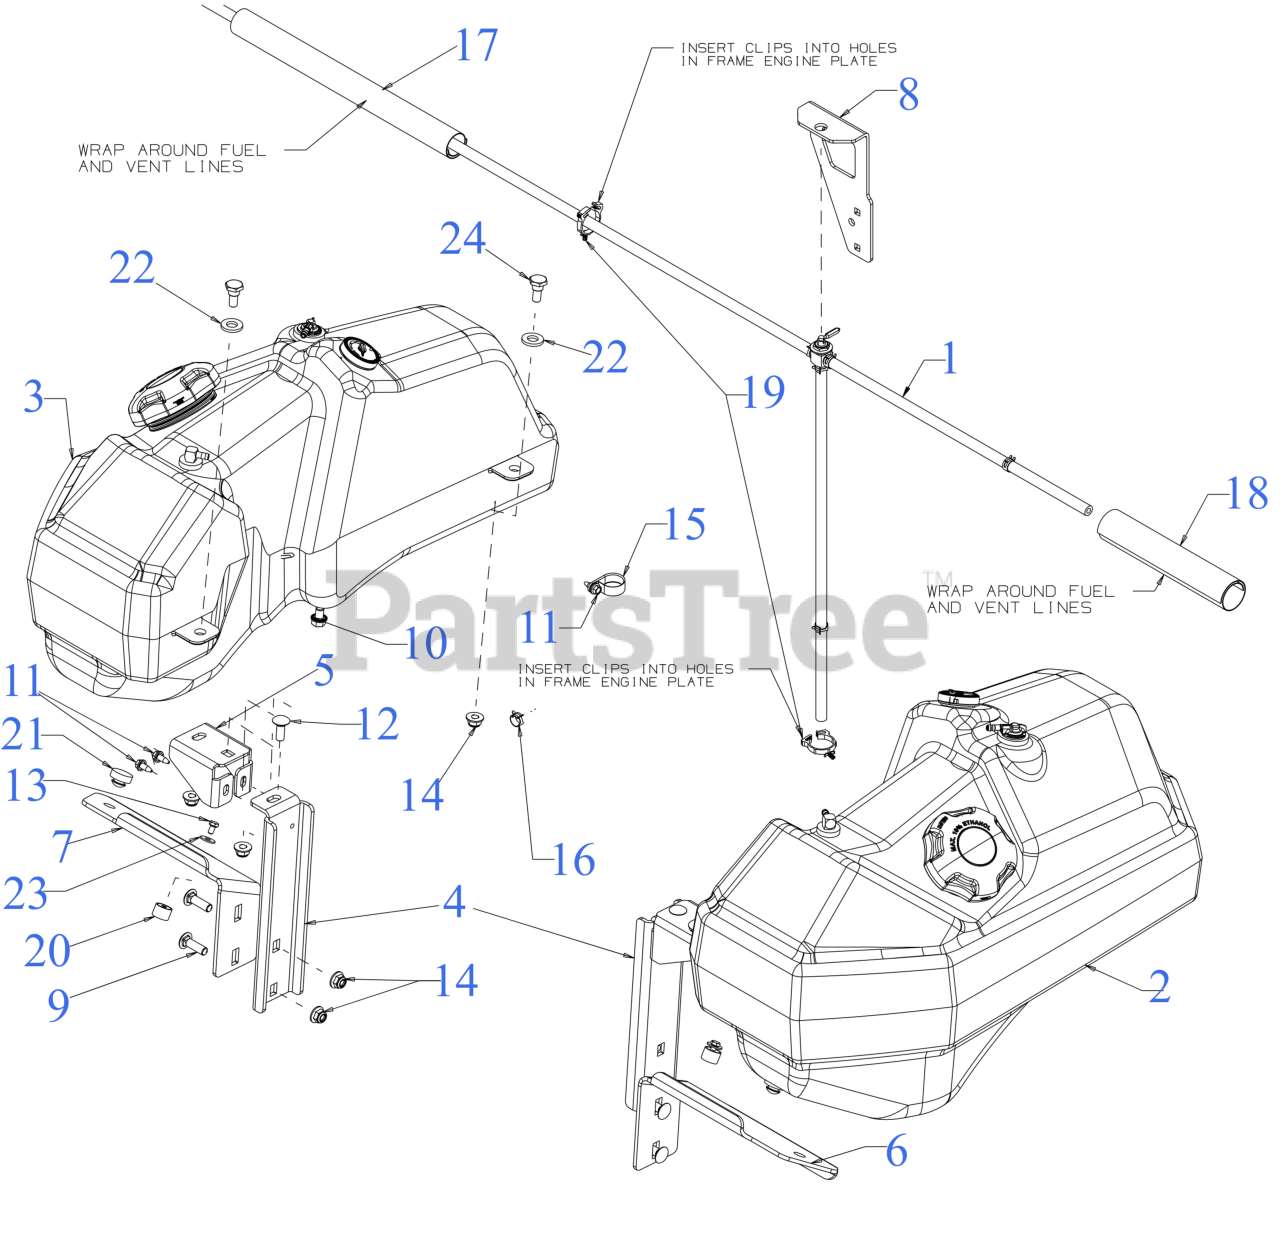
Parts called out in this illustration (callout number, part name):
1	FUEL HOSE W/VALVE EFI
1	HOSE CLAMP 1/20
2	TANK ASM (RH) (7.25 GAL)
2	FUEL TANK (7.25 GAL) (RH)
2	FUEL PICKUP VALVE (NO/SHUTOFF)
2	GROMMET-FUEL TANK
2	FUEL GAUGE
2	GROMMET .755 x .955 x .55
2	FUEL VENT FITTING
2	GROMMET 1.174X1.400X0.505
2	FUEL CAP - 3.50" ONE WAY VENT
3	TANK ASM (LH) (7.25 GAL)
3	FUEL TANK (7.25 GAL) (LH)
3	GROMMET-FUEL TANK
3	FUEL GAUGE
3	FUEL PICKUP VALVE (NO/SHUTOFF)
3	FUEL VENT FITTING
3	GROMMET .755 x .955 x .55
3	FUEL CAP - 3.50" ONE WAY VENT
3	GROMMET 1.174X1.400X0.505
4	FUEL TANK MOUNTING BRACKET
5	FUEL TANK MOUNTING BRACKET
6	LOWER FUEL TANK BRACKET (RH)
7	LOWER FUEL TANK BRACKET (LH)
8	VALVE MOUNT BRACKET
9	CARRIAGE BOLT 3/8-16 X1.25 GR5
10	SCREW 3/8-16 x .500 GR5
11	SCREW 1/4-20X.625
12	CARRIAGE BOLT 3/8-16 x 1.00 GR5
13	SCREW M6-1.0X10MM GR8.8
15	DRAIN HOSE CLAMP
17	WRAP AROUND SLEEVE 14"
18	WRAP AROUND SLEEVE 8"
21	RUBBER BUMPER 1.000 x .313
22	FLAT WASHER .510 x 1.000 x .125
23	FLAT WASHER
24	SHOULDER SCREW .498 DIA x .340
